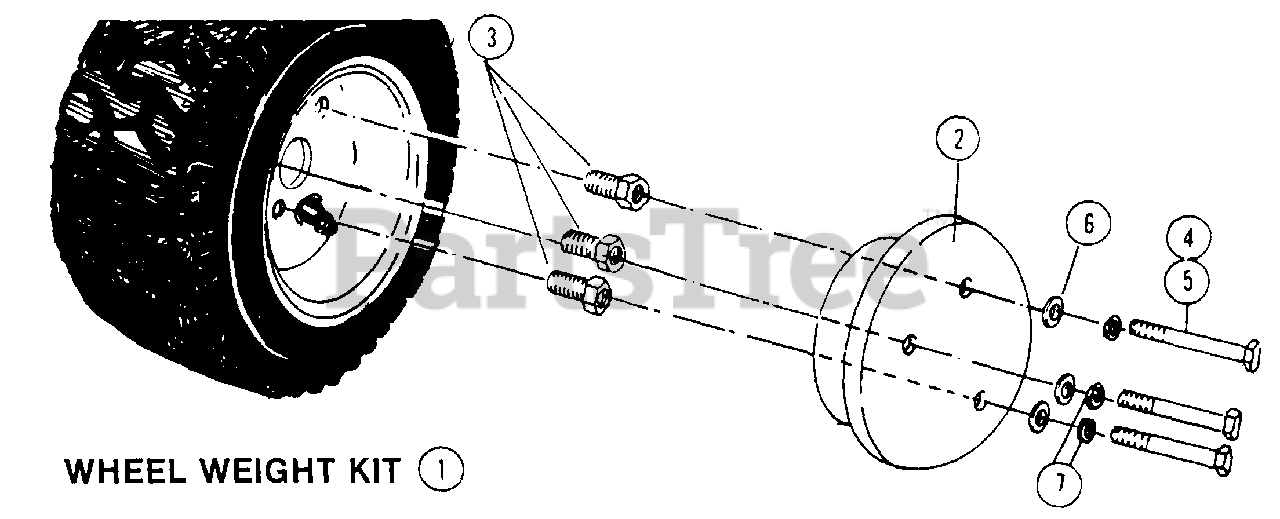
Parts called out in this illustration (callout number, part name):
1	KIT, Wheel Weight
2	WEIGHT, Wheel
3	STUD
4	CAPSCREW, 4-1/2 LONG
5	CAPSCREW, 3-1/4 LONG
6	WASHER, 3/8 SAE
7	LOCKWASHER, 3/8 SPLIT
